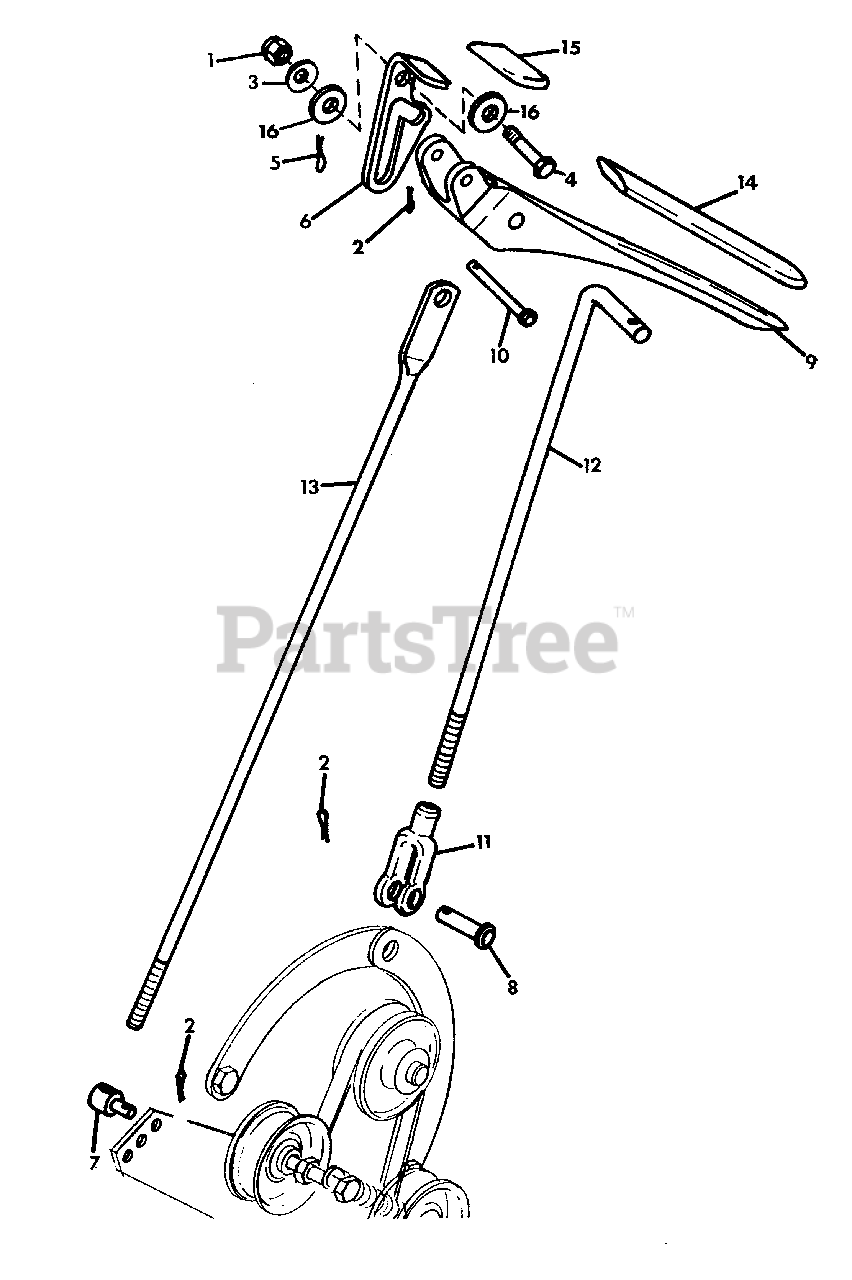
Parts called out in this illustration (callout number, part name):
1	Nut, Lock 1/4-20
2	Pin, Cotter .09x.625
3	Washer, Spring
4	Bolt, Hex 1/4-20x1.75
5	Pin, Cotter .06x.50
6	Lever, Clutch-Brake Lock R.H.
7	Pivot, Brake Rod
8	Pin, Clevis .312x.812
9	Lever, Hand Clutch
10	Pin, Clevis .187x1.70
11	Clevis, 5/16
12	Rod, Wheel Clutch Actuating
13	Rod, Brake
14	Grip, Handle
15	Tip, Vinyl
16	Washer, Friction
